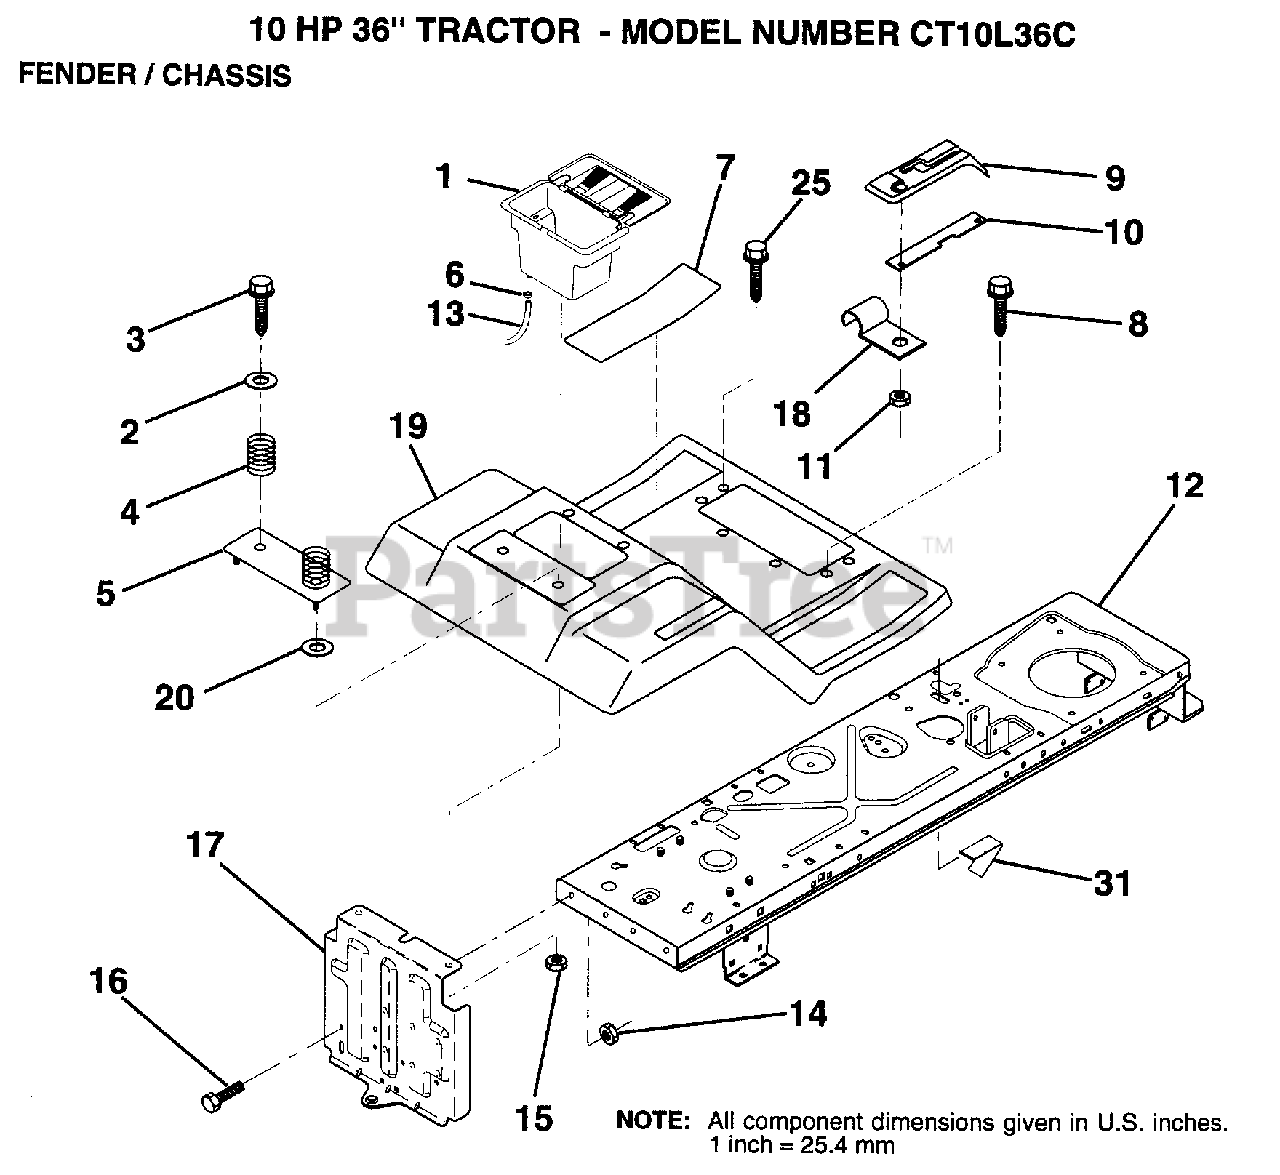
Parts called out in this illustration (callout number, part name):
2	WASHER
3	SCREW
4	SPRING COMPRESSIO
5	BTRY FENDER PLATE
6	HOSE CLAMP T
7	PAD FOOTREST
8	SCREW
9	CONSOLE SHFT 4SP
10	PLATE LOCK SHIFT
11	NUT
13	TUBE T
14	NUT
15	NUT
16	BOLT
17	DRAWBAR ASM LR
18	"CLIP,INSULATOR"
19	FENDER/FOOT MS505
25	SCREW TI
